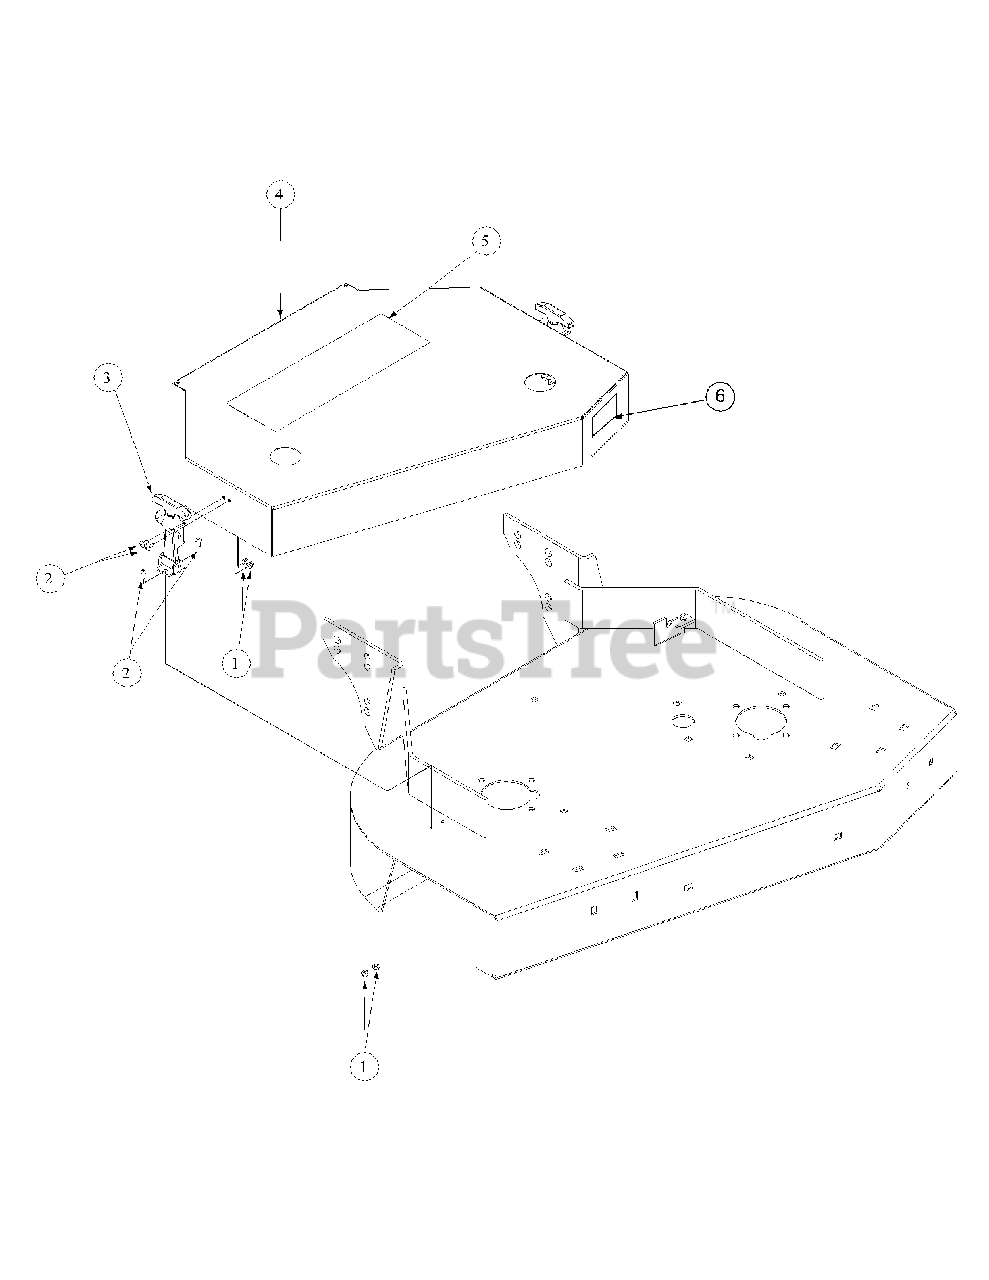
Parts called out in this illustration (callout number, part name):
1	Lock Nut, Nylon Insert
2	Machine Screw, 10-24 x 1/2
3	Rubber Hood Latch
4	Deck Cover, 36
5	Label Commercial Mower
6	Label, G1436
